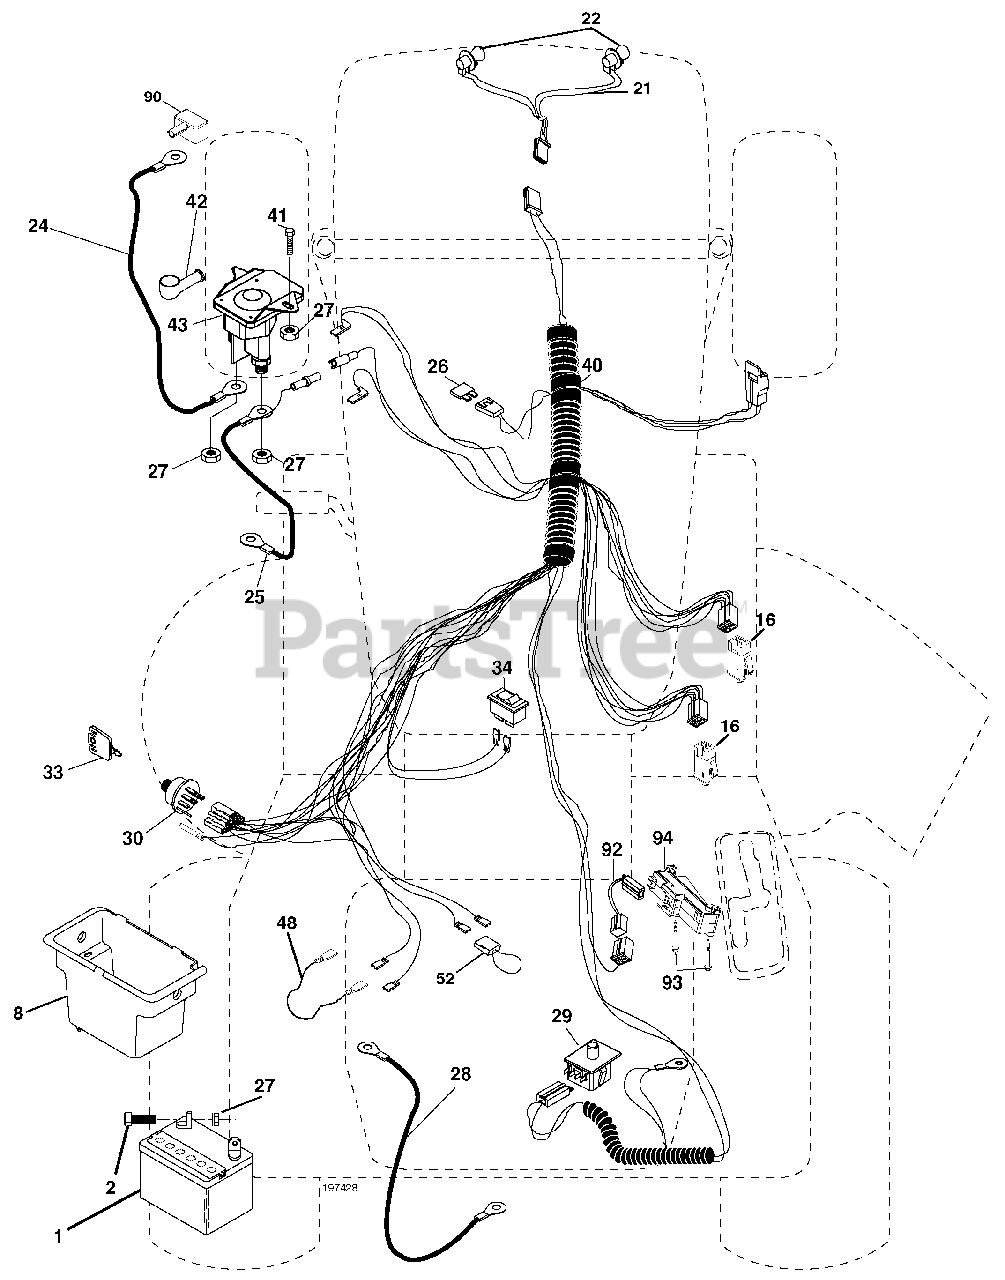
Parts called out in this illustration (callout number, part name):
1	Battery
2	Bolt Hex Hd 1/4-20 unc x 3/4
8	Box Battery
16	Switch Interlock
21	Harness Asm Light W/4152j
22	Bulb Light #1156
24	Cable Battery 6 Ga. 11"red
25	Cable Battery
26	Fuse 20 AMP
27	Nut Keps Hex 1/4-20 unc
28	Cable Ground 6 Ga. 12"black
29	Switch
30	Switch Ign
33	Key Ign
34	Switch Light/Reset
40	Harness Ign
41	Bolt Blk Fin Hex 1/4-20
42	Cover Terminal Red
43	Solenoid
48	Adapter Ammeter
52	Protection Wire Loop
90	Cover Terminal Battery
92	Harness Pigtail
93	Screw Plastite 10-14 x 2.0
94	Module Reverse
